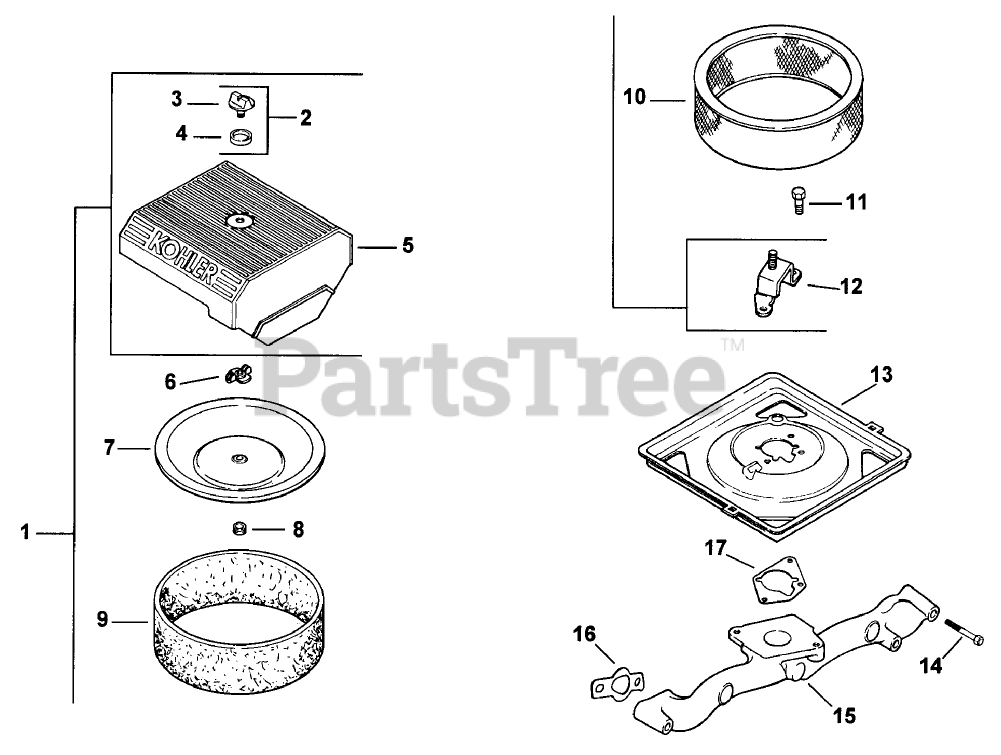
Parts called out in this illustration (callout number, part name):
1	Kit, air cleaner cover (Includes 2-5,12)
2	Kit, knob w/seal (Includes 3,4)
3	Knob-Cover
4	O-Ring
5	Cover-Air Cleaner
6	Wingnut
7	Cover-Inner AirCleaner
8	Seal
9	Precleaner-Element
10	Element, air cleaner
11	Screw
12	Bracket-Air Cleaner
13	Base, air cleaner
14	Screw
15	Manifold
16	Gasket-Intake, Manifold
17	Gasket
